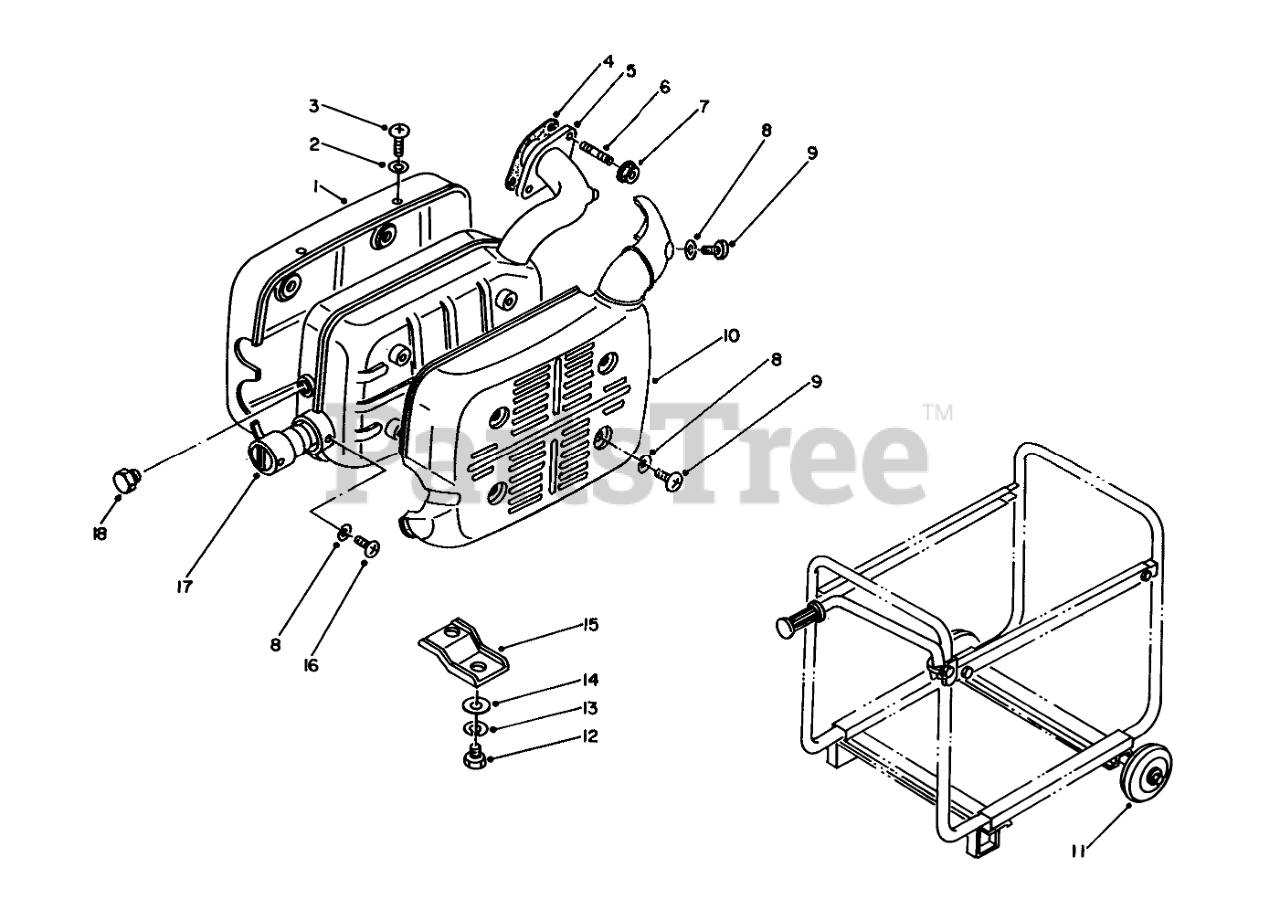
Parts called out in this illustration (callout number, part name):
1	Cover-Rear
2	Lockwasher
3	Screw
4	Gasket-Exhaust
5	MUFFLER ASSM
6	Stud Bolt
8	Lockwasher
9	SCREW
10	Cover-Front
11	Wheel Assembly (Optional)
13	WASHER-LOCK
14	Washer
15	Bracket-Muffler
16	Screw
17	Cleanout Tube
18	Drain Plug
